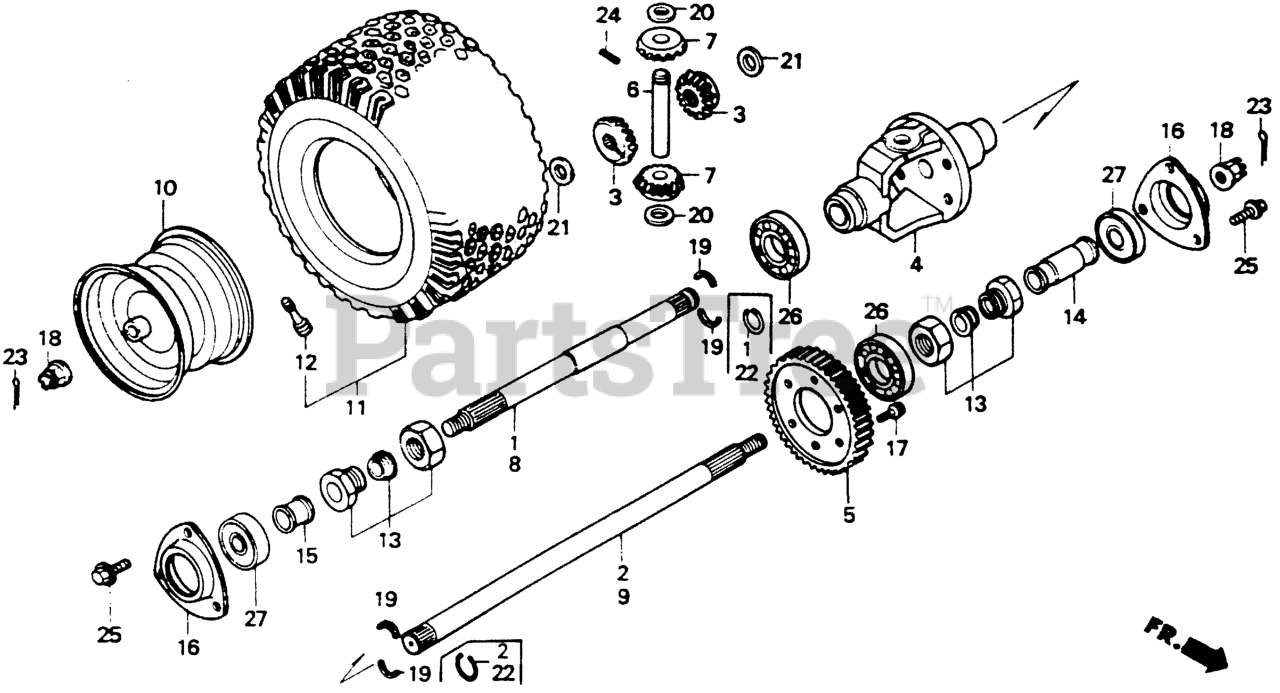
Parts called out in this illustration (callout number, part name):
3	GEAR, DIFFERENTIAL
4	CASE, DIFFERENTIAL GEAR
5	GEAR, FINAL DRIVEN (48T)
6	SHAFT, DIFFERENTIAL
7	PINION, DIFFERENTIAL
8	SHAFT, R. AXLE
9	SHAFT, L. AXLE
10	WHEEL, RR.
11	TIRE ASSY., RR. (OHTSU)
12	VALVE, RIM
16	HOLDER, BEARING
17	BOLT, SPECIAL (10X20)
18	NUT, AXLE (14MM)
19	COTTER (15MM)
20	WASHER A, DIFFERENTIAL PINION (14.2X26X0.7)
20	WASHER B, DIFFERENTIAL PINION (14.2X26X0.8)
20	WASHER C, DIFFERENTIAL PINION (14.2X26X0.9)
20	WASHER D, DIFFERENTIAL PINION (14.2X26X1.0)
21	WASHER, DIFFERENTIAL GEAR
23	PIN, SPLIT (3.0X25)
23	PIN, COTTER (3.0X45)
24	PIN, SPRING (4X32)
25	BOLT, FLANGE (8X14)
26	BEARING, RADIAL BALL (6006)
27	BEARING, RADIAL BALL (6204UU)
